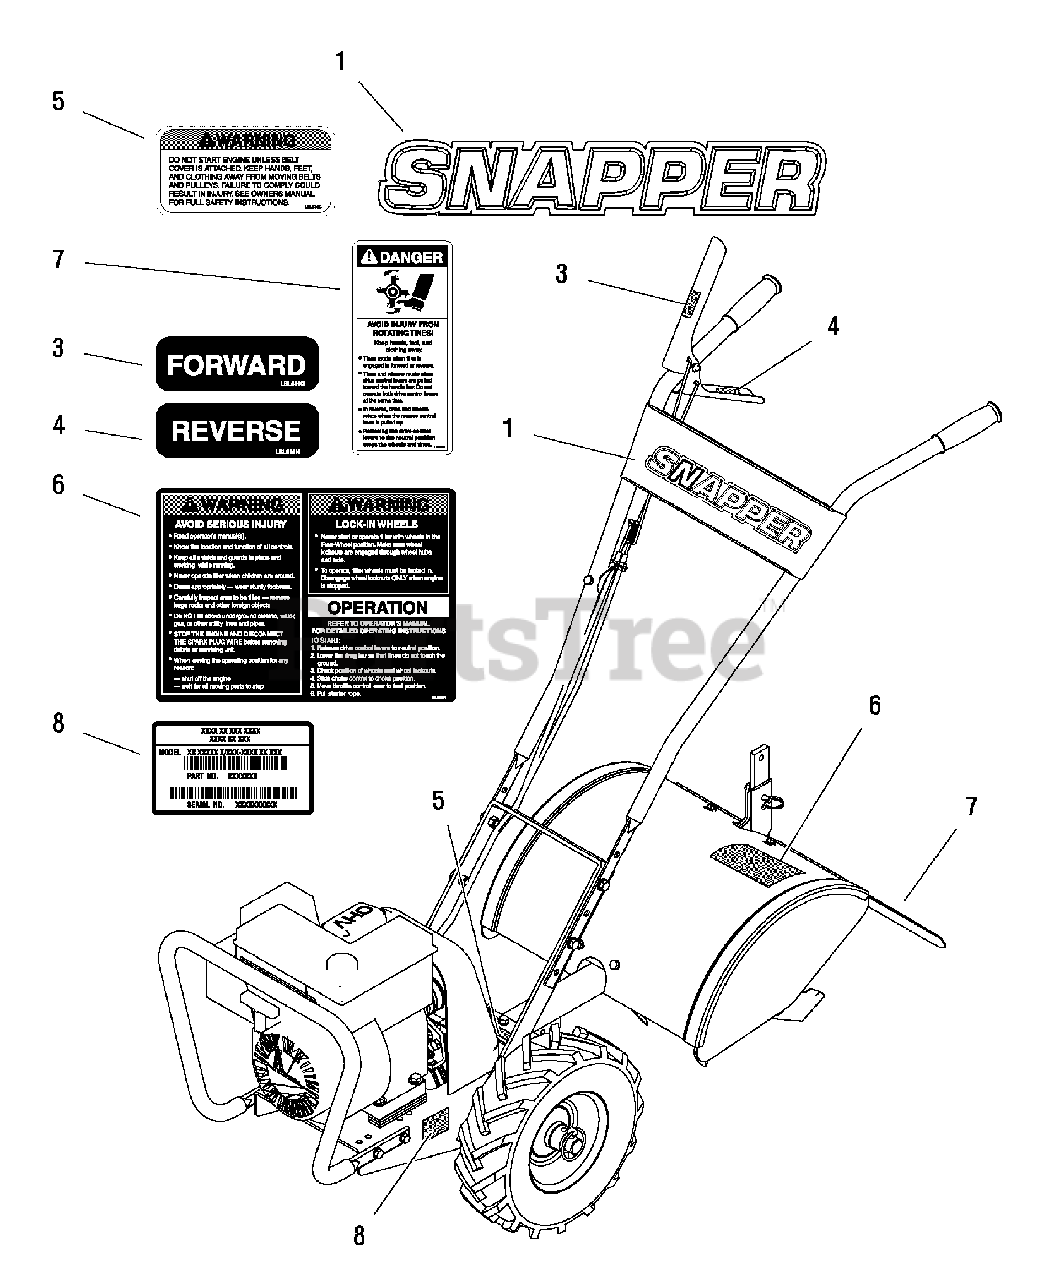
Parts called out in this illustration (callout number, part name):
1	DECAL, SNAPPER
2	DECAL SHEET, Common Warning 6016RT Tillers
3	* DECAL, Forward Instructions
4	* DECAL, Reverse Instructions
5	* DECAL, Warning, Belt Cover
6	* DECAL, Hood, Operator Instructions Label
7	* DECAL, Danger, Rotating Tines
8	** DECAL, Serial Number
